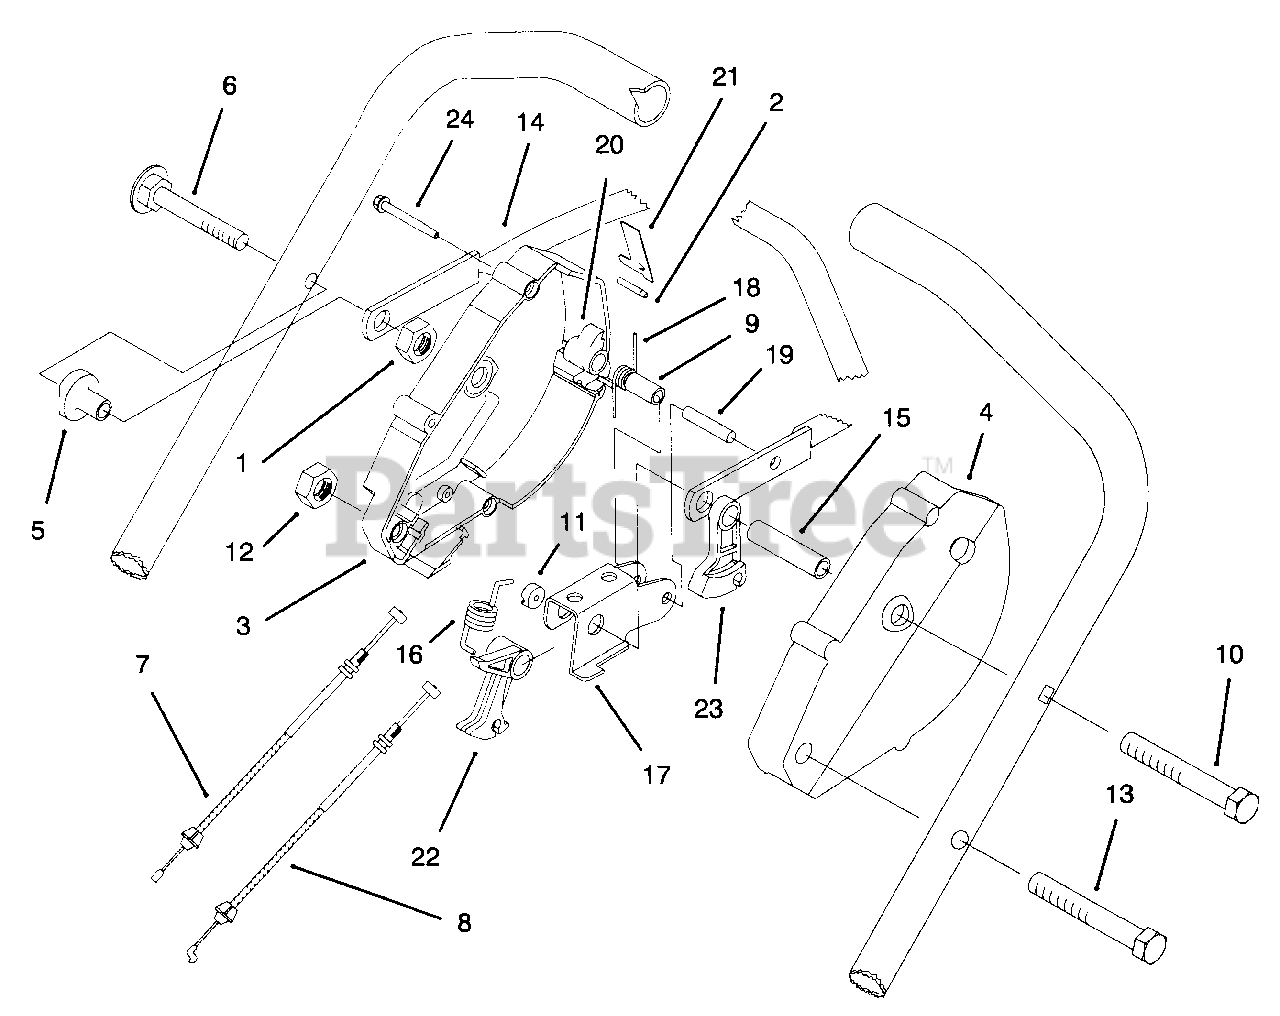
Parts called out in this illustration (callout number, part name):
1	Nut-Flange Nylon
2	Pin-Insert
3	Housing-Control R.H.
4	Housing-Control L.H.
5	Spacer-Support
7	Cable-BBC
8	Cable-Traction
9	Bushing-PM
10	Screw-Handle
11	Washer-Nylon
12	Nut-Lock
13	Screw-Handle
14	Bar-Control
16	Spring-Detent
18	Spring-Torsion
19	Pin-Roll
20	Hook-Control
21	Spring-Leaf
22	Lever-Cable
23	Lever-Traction
24	Screw-Hex Washer Hd.
